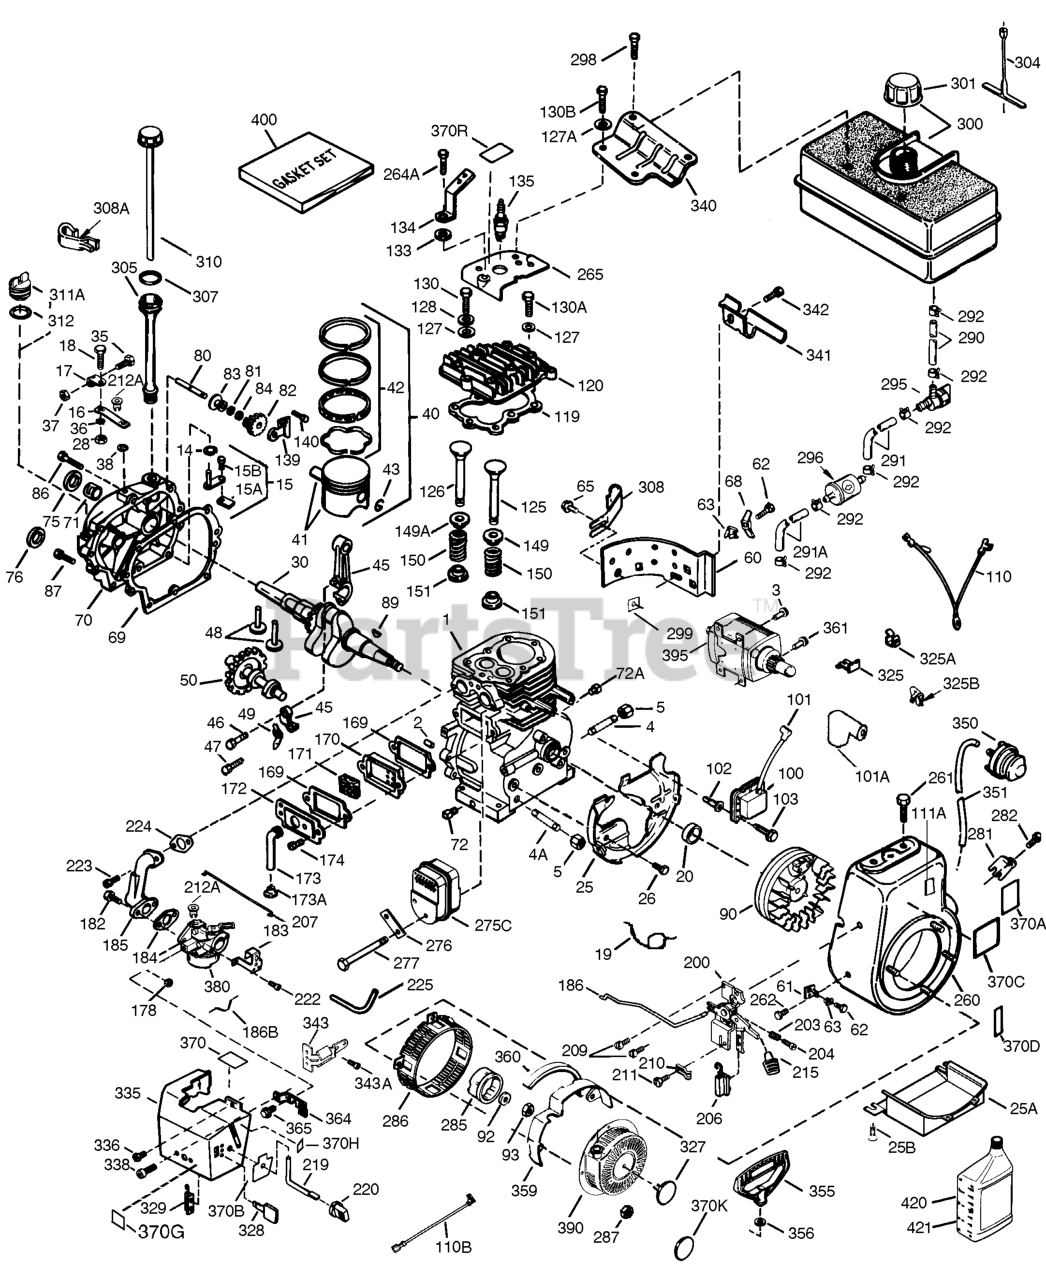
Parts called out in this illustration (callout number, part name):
1	CYLINDER
4	PIPE NIPPLE
5	PIPE CAP
15	GOVERNOR ROD
15A	GOV YOKE
16	GOV LEVER
18	SCREW
20	OIL SEAL
25	BAFFLE
30	CRANKSHAFT
38	RET RING
40	PISTON ASSY 020
40	PISTON ASSY 010
40	PISTON ASSY STD
41	PISTON ASSY 020
41	PISTON ASSY STD
41	PISTON ASSY 010
42	RING SET 020
42	RING SET 010
42	RING SET STD
43	RET RING
45	CONN ROD
46	SCREW
47	SCREW
48	VALVE LIFTER
49	OIL DIPPER
50	CAMSHAFT
60	EXTENSION
61	BRACKET
63	GROMMET
69	GASKET
70	CYL COVER
71	BUSHING
80	GOV SHAFT
83	GOV SPOOL
84	RET RING
90	FLYWHEEL
100	LAMINATION
101	PLUG COVER
102	STUD
103	SCREW
110	GROUND WIRE
120	CYL HEAD
125	EXH VALVE OS
125	EXH VALVE STD
126	INTAKE VALVE OS
126	INT VALVE ST
128	WASHER KIT
131A	SCREW
135	SPARK PLUG
139	BRACKET
140	SCREW
149	VALVE CAP
149A	INT VALVE SEAL
150	VALVE SPRING
151	VALVE CAP
170	BREATHER
171	ELEMENT
172	VALVE COVER
183	BRACKET
185	INTAKE PIPE
186	GOV LINK
200	CONTROL ASSY
203	COMP SPRING
204	SCREW
206	TERMINAL
207	GOV LINK
219	CHOKE ROD
222	SCREW
260	BLOWER HSG
265	COVER
275C	MUFFLER
276	LOCK PLATE
285	STARTER CUP
290	FUEL LINE
300	FUEL TANK
301	FUEL CAP
305	FILLER TUBE
310	DIPSTICK
327	STARTER PLUG
328	KEY
335	CARB COVER
340	TANK BRACKET
341	TANK BRACKET
343	BRACKET
350	PRIMER
351	PRIMER LINE
355	START HANDLE
364	BRACKET
380	CARBURETOR
390	STARTER
400	GASKET SET
420	OIL SAE 5W30
